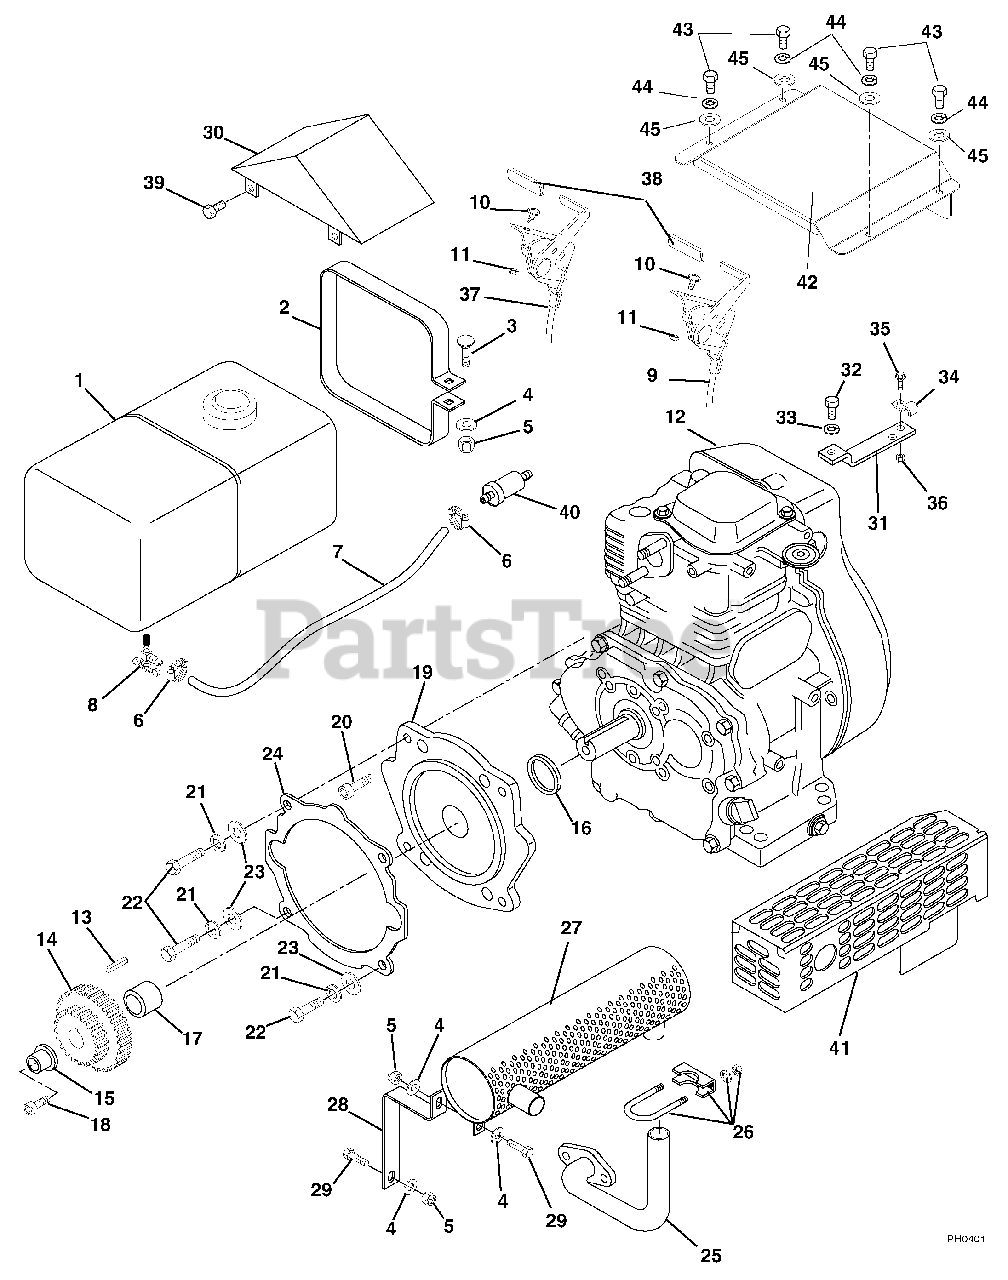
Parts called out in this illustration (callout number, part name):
1	Tank, Gas with Cap
2	Strap-Fuel Tank
3	Bolt-Round Head Square Neck .25-20 x 1.75
4	Washer-Flat-Steel .281 x .620 x .065
5	Nut-Locking-Center .250-20 Grade 2
6	Clamp-Hose
7	Gas Line-Bulk
8	Valve & Strainer
9	Cable-Control (Throttle) (117, 309, 311, 312)
9	Control, Throttle (119)
10	Screw-Machine 10-24 x .50
11	Nut-Locking Nylon 10-24
12	Engine-13.5HP Robin EH41 (117, 309, 311, 312)
12	Engine-12HP Kohler Command Pro CS125T (119)
13	Key-Square .248 x 1.0 x .248
14	Gear
15	Pilot-Gear
16	Seal 1.188 x 2.000 x .250 (117, 309, 311, 312)
16	Seal 1.375 x 2.000 x .315 (119)
17	Spacer-Steel 1.00 x 1.31 x .836
18	Screw-Machine .38-24 x 1.00
20	Screw-Socket Head .38-16 x 1.00
21	Washer-Lock .438 x .133
22	Bolt-Hex .44-14 x 1.50
23	Washer-Flat-Steel .469 x .938 x .065
24	Gasket-Chassis to Adapter
25	Manifold (117, 309, 311, 312)
25	Weldment- Exhaust Pipe (119)
26	Clamp-Muffler 1.25
27	Muffler
28	Bracket-Exhaust
29	Bolt-Hex .25-20 x 1.00 Grade 5
30	Panel-Linkage Cover (117, 309, 311, 312)
31	Bracket-Cable Mount (117, 309, 311, 312)
32	Bolt-Hex M6 x 1.00 x 20 (117, 309, 311, 312)
33	Washer-Locking .25 x .062 Regular (117, 309, 311, 312)
34	Clip-Cable (117, 309, 311, 312)
35	Screw-Machine Hex Washer Head 10-24 x .75 (117, 309, 311, 312)
36	Nut-Locking-Nylon 10-24 w/ Insert (117, 309, 311, 312)
37	Cable-Control (Choke) (117, 309, 311, 312)
37	Cable, Choke (119)
39	Bolt-Hex M8 x 1.25x16 (117, 309, 311, 312)
40	Filter-Fuel
41	Weldment-Muffler Guard (309, 311, 312)
42	Cover-Fuel Pump (119)
43	Bolt-Hex M6 x 1.0 x 12 (119)
44	Washer-Lock .25 x .062 (119)
45	Washer-Flat-Steel .250 x .562 x .049 (119)
